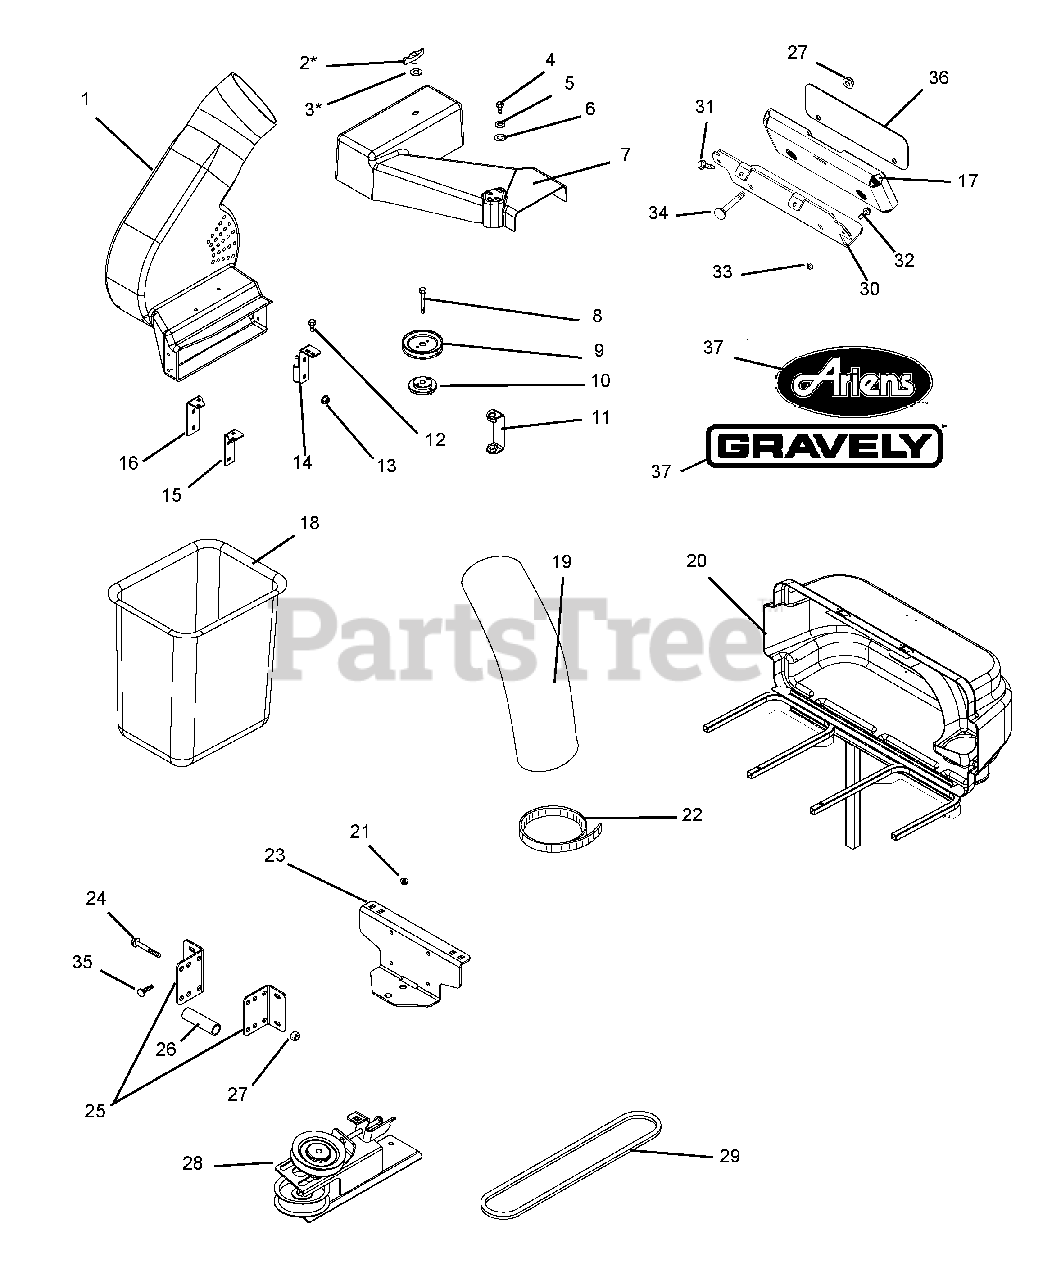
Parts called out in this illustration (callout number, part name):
1	Blower Assembly
2	Wing Knob
3	3/8" x 1-1/2" Washer
4	3/8" x 3/4' Hex Bolt
5	3/8" Lock Washer
6	7/16" x 1" Flat Washer
7	Belt Cover
8	3/8" x 1-3/4" Hex Bolt
9	3-Inch Sheave
9	4-Inch Sheave
10	Sheave Adapter
11	Cover Spacer
12	1/4" x 3/4" Hex Bolt
13	1/4" Top Lock Flange Nut
14	Rear Mount Weldment Bracket
15	Front Bracket
16	Front Mount Weldment Bracket
17	Counterweight
18	Grass Bagger Basket
20	Cover Assembly
21	3/8" Top Lock Flange Nut
22	Hose Clamp
23	Trailer Hitch
24	1/2" x 3" Hex Bolt
25	Bagger Mount Bracket
26	Pivot Spacer
27	1/2" Top Lock Flange Nut
28	Idler Assembly
29	44-Inch V-Belt
29	48-Inch V-Belt
30	Counterweight Bracket
31	3/8" x 3/4" Self-Tapping Screw
32	3/8" x 1-1/4" Hex Bolt
33	3/8" Top Lock Flange Nut
34	1/2" x 5" Round Head Square Neck Bolt
35	3/8" x 3/4" Round Head Square Neck Bolt
36	Decal Panel
37	Gravely Decal
